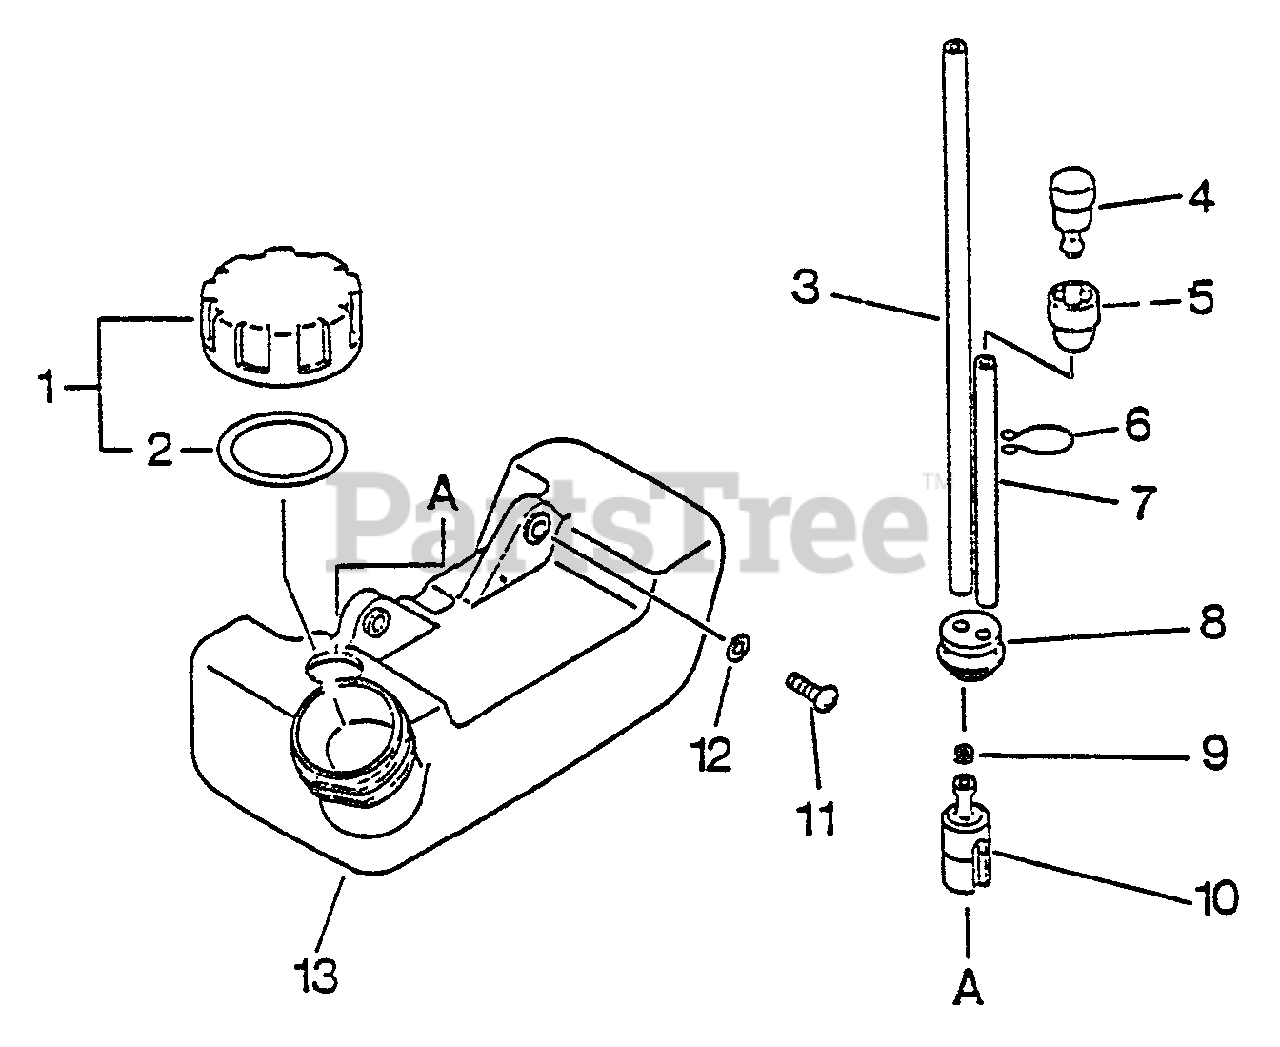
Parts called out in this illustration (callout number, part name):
1	CAP ASSY
2	GASKET, FUEL CAP
3	PIPE, FUEL 3x-5x-180
4	VENT ASSY
5	HOLDER, VENT
6	CLIP, TUBE
7	PIPE, FUEL RETURN 3×6×70
8	GROMMET, FUEL
9	CLIP 6 MM
10	FILTER, FUEL
11	SCREW 5×16
12	WASHER 5.5×12×0.8
13	TANK, FUEL
